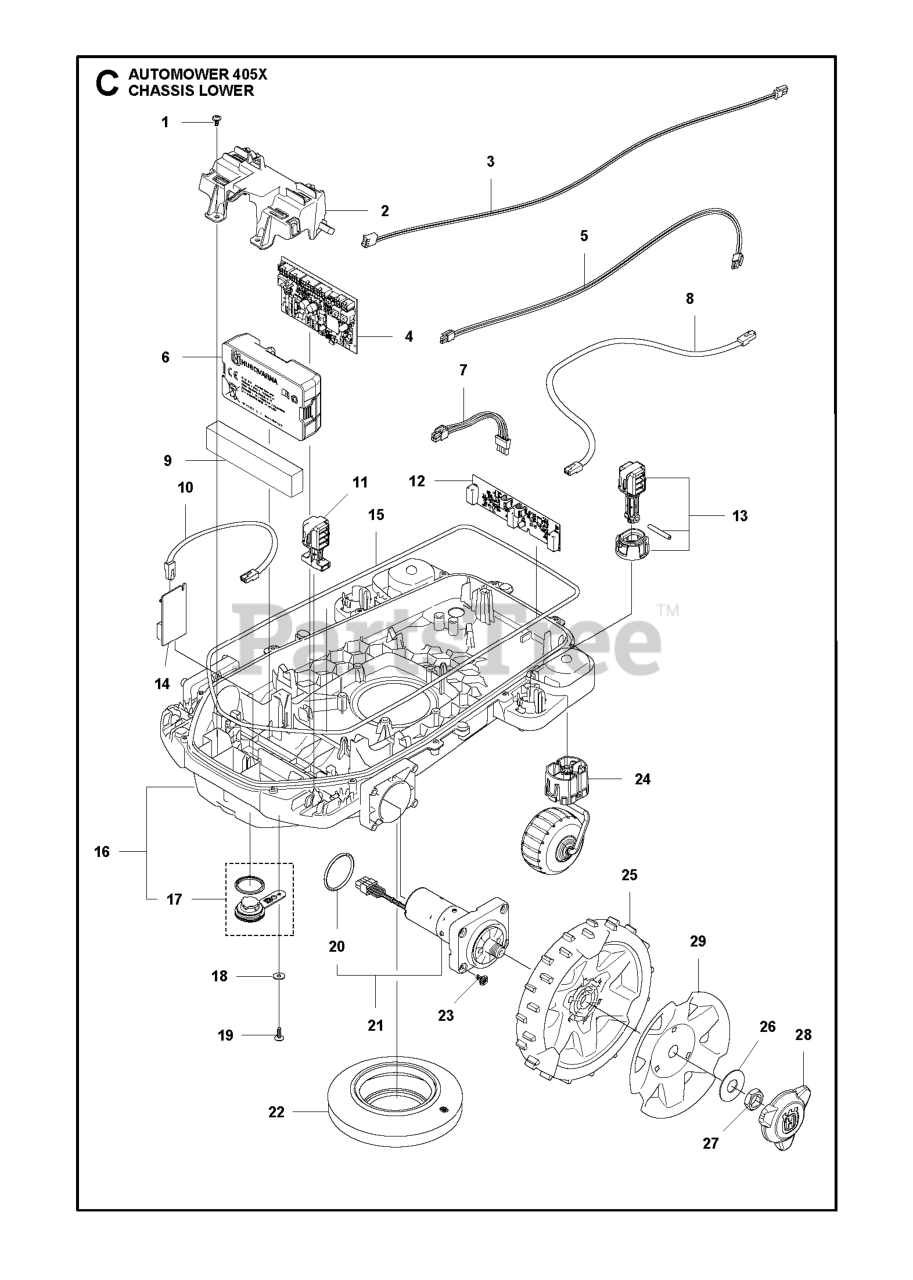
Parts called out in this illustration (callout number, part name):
1	SCREW ITXPANT
2	CLAMP REAR - P16
3	WIRING ASSY LED LIGHT EXTENSIO
4	Circuits
5	WIRING ASSY BATTERY CHARGING A
6	BATTERY SPAREPART KIT BATTERY
7	WIRING ASSY BATTERY CABLE PREM
8	WIRING ASSY MODULAR JACK 6/6 R
9	WEIGHT SQUARE BAR
11	STRUT TILT
12	PRINTED CIRCUIT ASSY LOOP RECE
13	COLUMN ASSY P16
14	PRINTED CIRCUIT ASSY PCBA LOOP
15	SEALING STRIP CHASSIS LOWER P1
16	CHASSIS LOWER - P16
19	SCREW ITXPANT
20	O-RING LIGHT GREY
22	BELLOWS CUTTING SYSTEM
23	SCREW ITXPANT
24	WHEEL ASSY SPINDLE INSIDE 2K
26	WASHER WASHER REAR WHEEL 16X40
27	HEXAGON THIN NUT
28	HUB CAP REAR WHEEL NO CENTER P
29	WHEEL COVER PAINTED
